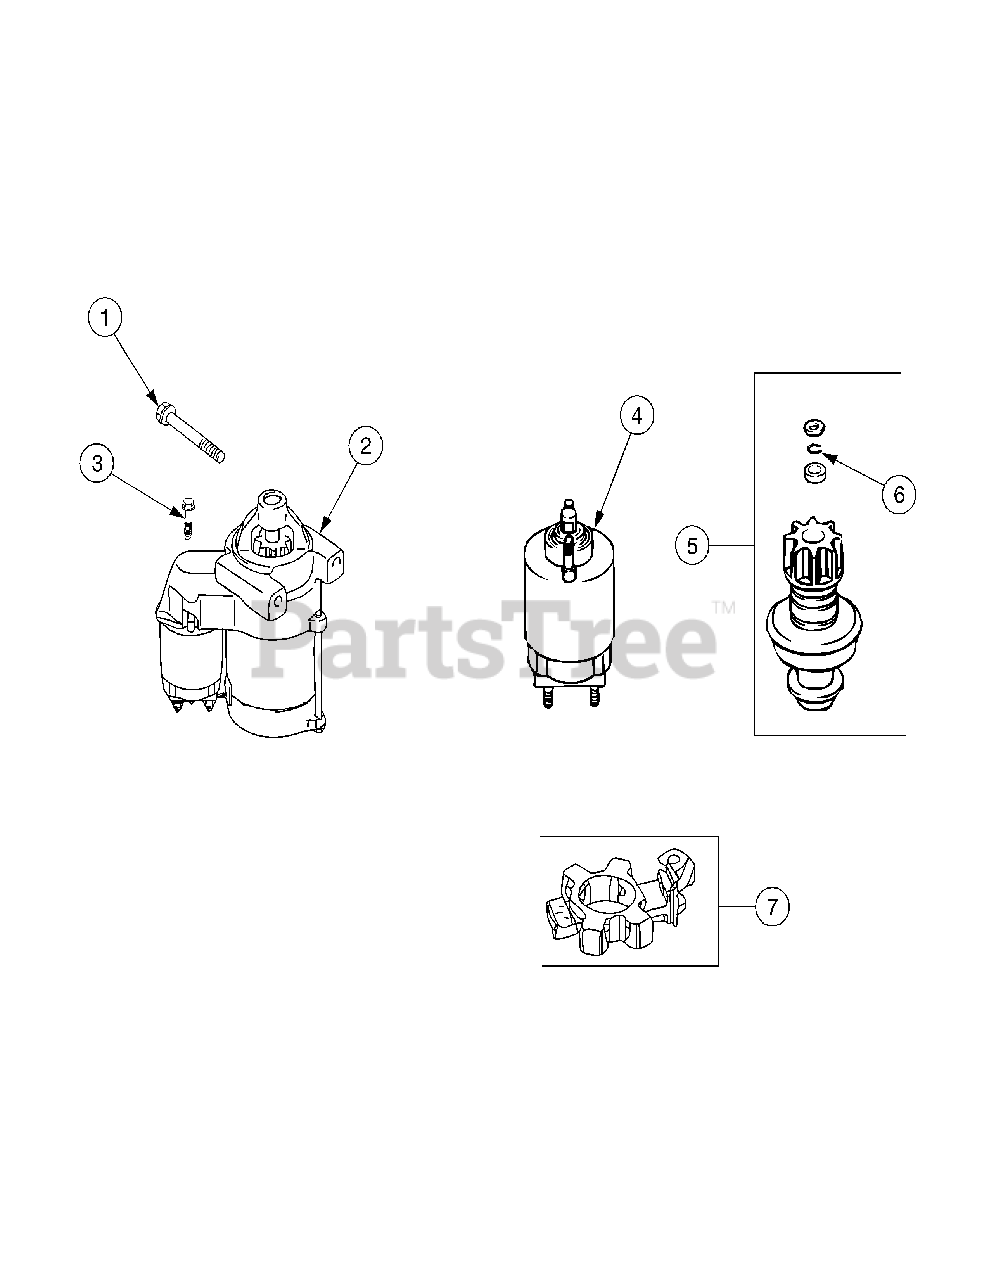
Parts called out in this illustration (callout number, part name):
1	Screw, Hx Flange, M8-1.25 x 80
2	Starter, Solenoid Shift
3	Screw, Torx Hd
4	Kit, Solenoid
5	Kit, Starter Pinion
